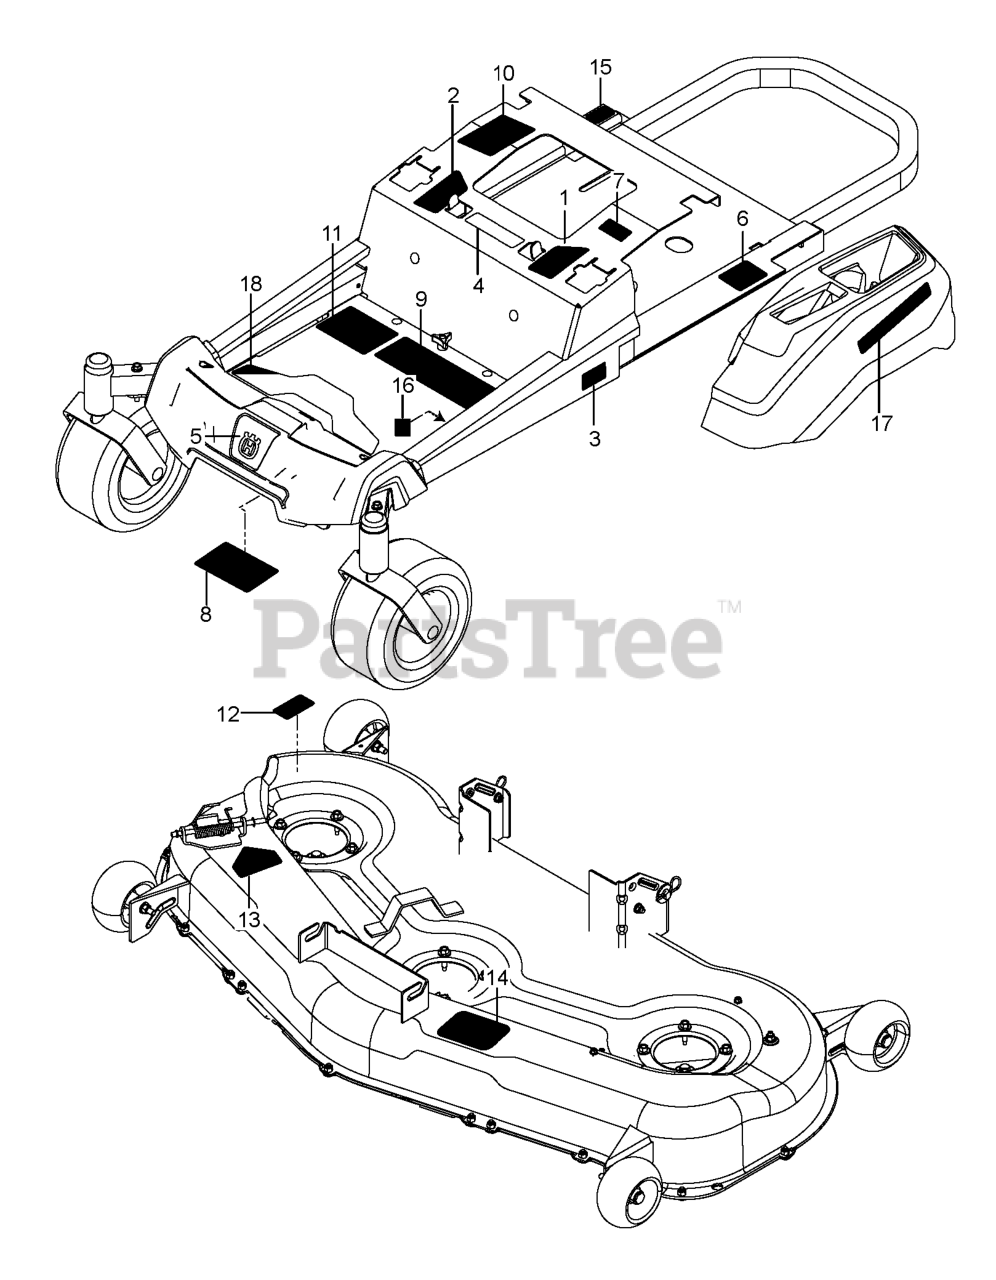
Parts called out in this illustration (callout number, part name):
1	DECAL.ZTR.RZ.THRTL/PRKBRK.V2.L
2	DECAL.ZTR.RZ.THRTL/PRKBRK.V2.R
3	DECAL.ZTR.SIDE.RAIL.GRAPHIC
4	EURO DECAL-BATTERY WARNIN6
5	DECAL.BADGE.55MM.CROWNH.HUSQ
6	DECAL, DO NOT TOW
7	DECAL, EXITING MOWER
8	DECAL, SERVICE
9	DECAL.ZTR.WARNING.SMARTIGNITIN
10	DECAL, CUSTOMER RESPNSIBILITY
11	DECAL.ZTR.STARTINSTRCT.CHOKE15
12	DECAL.DECK.6MIL./DEF.SHLD.WARN
13	DECAL, DECK DEFLECTOR, WARNING
14	DECAL, BELT ROUTING
15	DECAL CERTIFICATION DECAL EMCC
16	DECAL.80.DBA.AUSTRALIA
17	DECAL.HUSQVARNA.210MM
18	PAD.RZ.FOOTREST.PLATE
